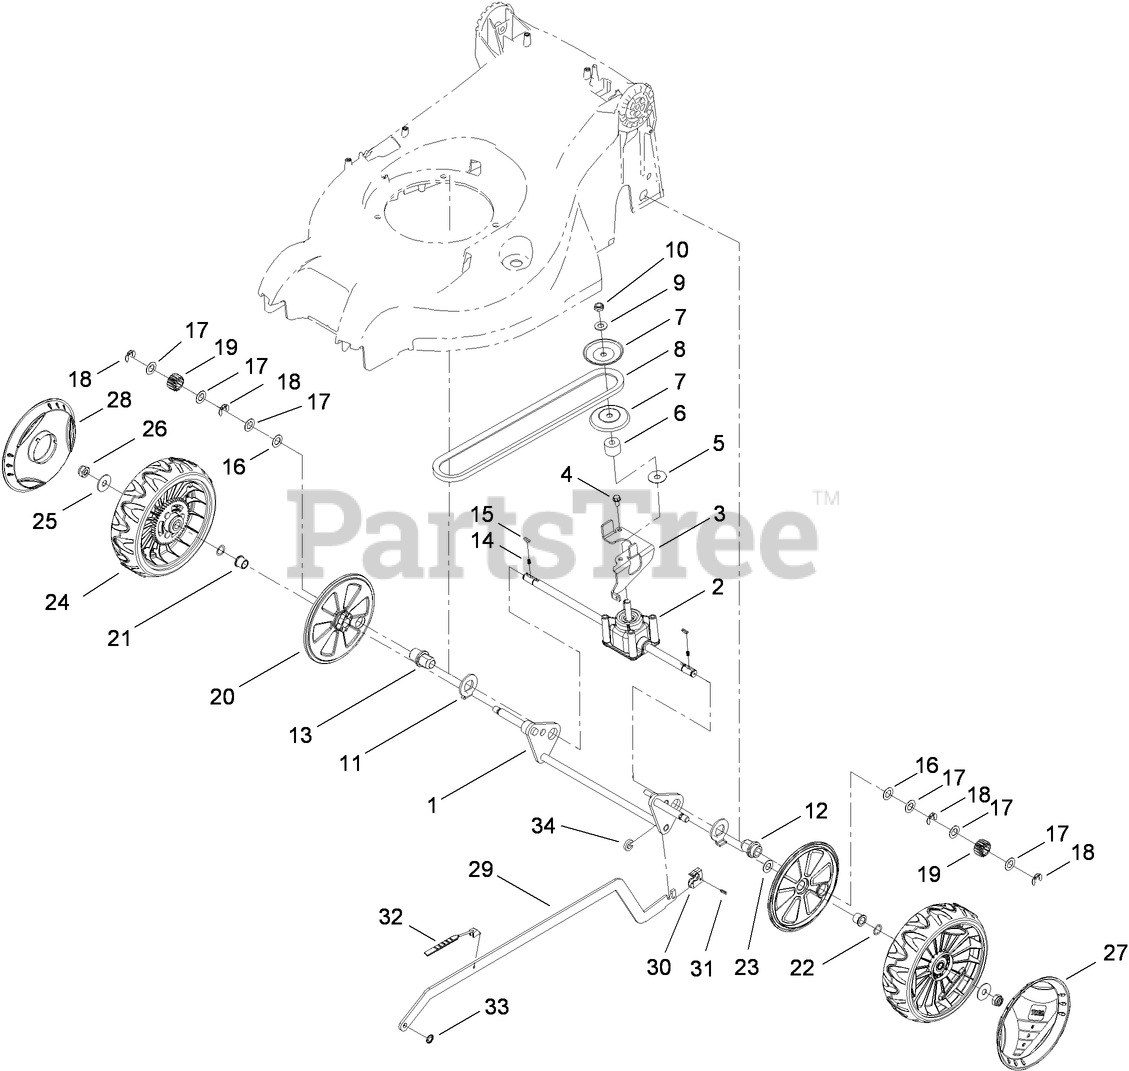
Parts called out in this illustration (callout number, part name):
1	PIVOT BAR ASM
4	SCREW-HWH
5	WASHER-PLAIN
6	SPACER
7	PULLEY-HALF
8	V-BELT
9	WASHER-FLAT
10	NUT-HEX
11	CLIP-BUSHING
14	SPRING-COMPRESSION
16	WASHER-PLAIN
17	WASHER-THRUST
18	RING-RETAINING,CLIP
19	GEAR-PINION, 15T
20	COVER-WHEEL, INNER
21	HUB-AXLE, REAR
22	WASHER-SPRING
23	WASHER-PLAIN
25	WASHER-PLAIN
26	NUT-HH
27	COVER-WHEEL, SMART WHEEL
28	COVER-WHEEL, REAR
30	CLIP-BAR, CONNECTION
31	PIN-GROOVE
32	SCALE-HOC
33	CLIP-PUSH
34	RING-FIXING
